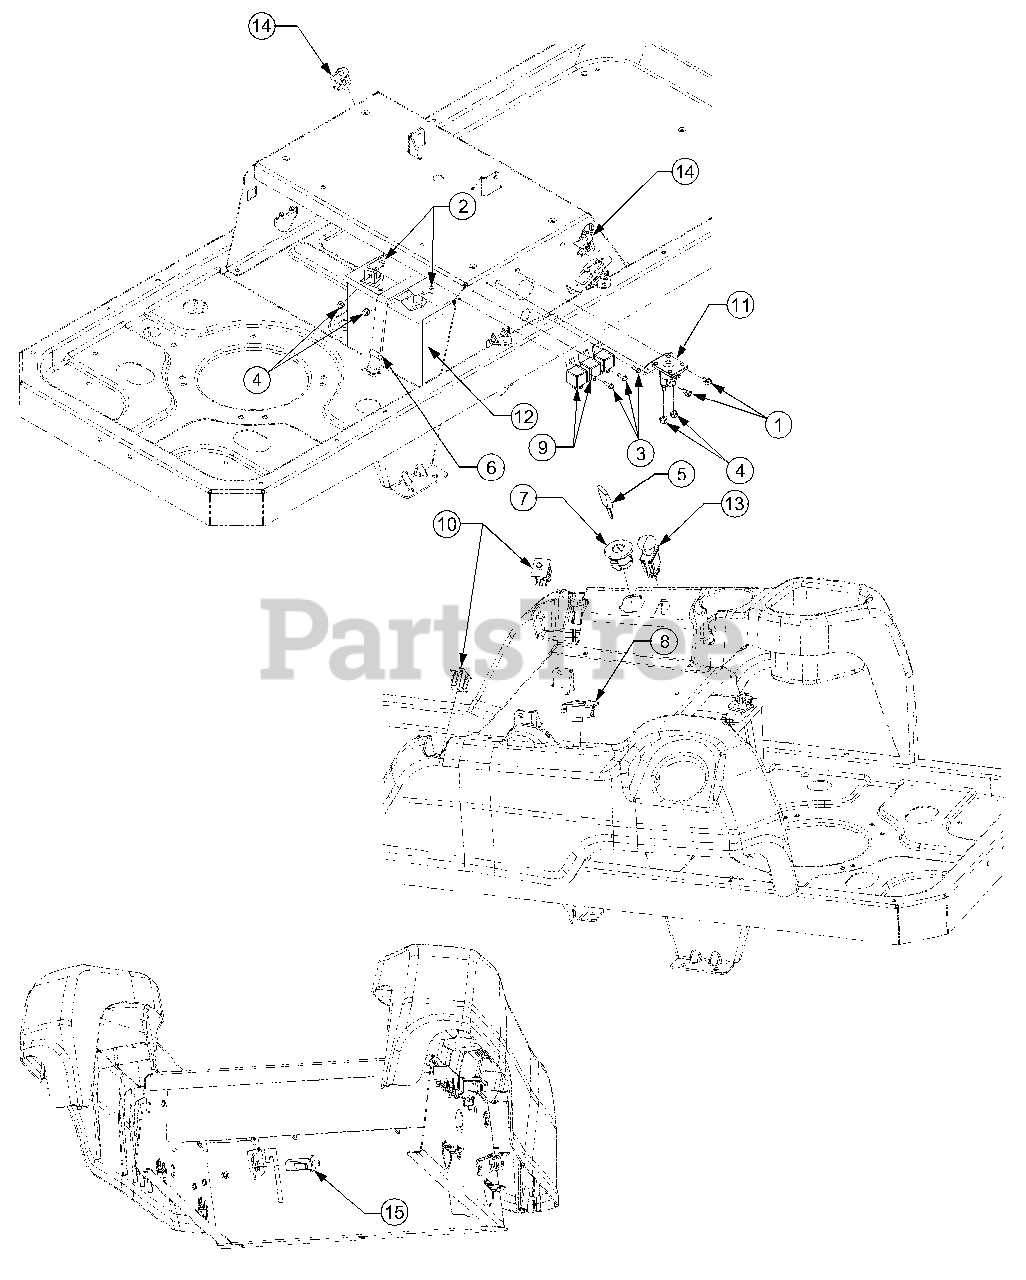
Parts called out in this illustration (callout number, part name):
1	Screw, Hex Wash. Hd. Tapp, 1/4-20 x .5
2	Screw, Hex Cap, 1/4-20 x .75 GR5
3	Screw, Hex Wash. Hd. Tapp #10-32 x .625
4	Nut, Hex Sems, 1/4-20
5	Key
6	Strap, Battery
7	Switch, Ignition
8	Meter, Hour
9	Relay
10	Switch, Dbl. Pole - Neutral
11	Solenoid
12	Battery, 245 CCA
13	Switch, PTO
14	Switch, Snap Mount (N.C.) - Reverse
15	Switch, Plunger, (N.O./N.O.) - Brake
